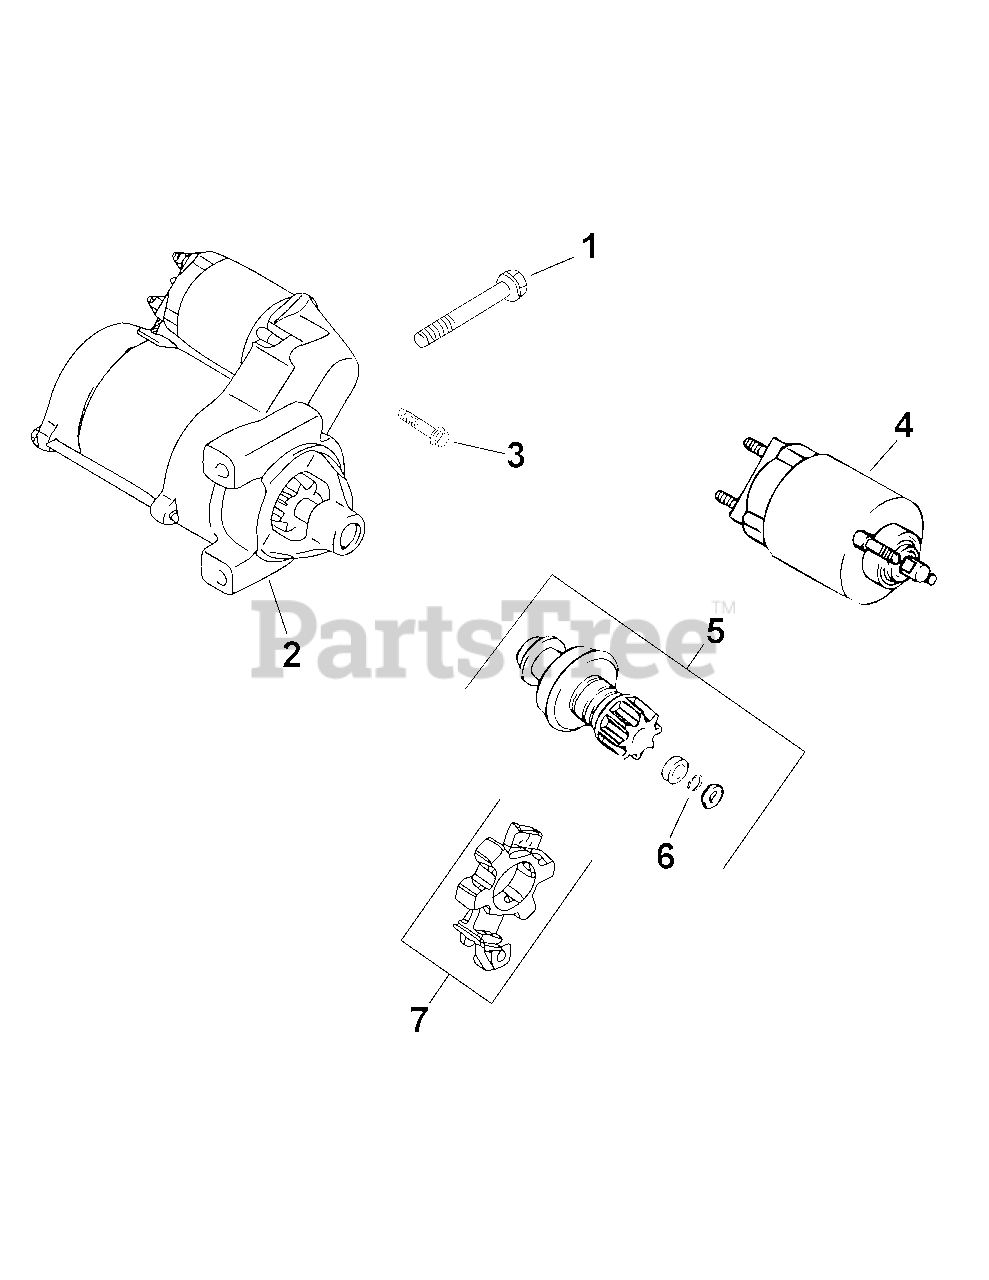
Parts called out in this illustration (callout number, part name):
1	Scr, hex flange M8x1.25x80
2	Starter, solenoid ass’y
3	Screw, external torx hd.
4	Kit, solenoid
5	Kit, starter pinion
7	Brush, holder
